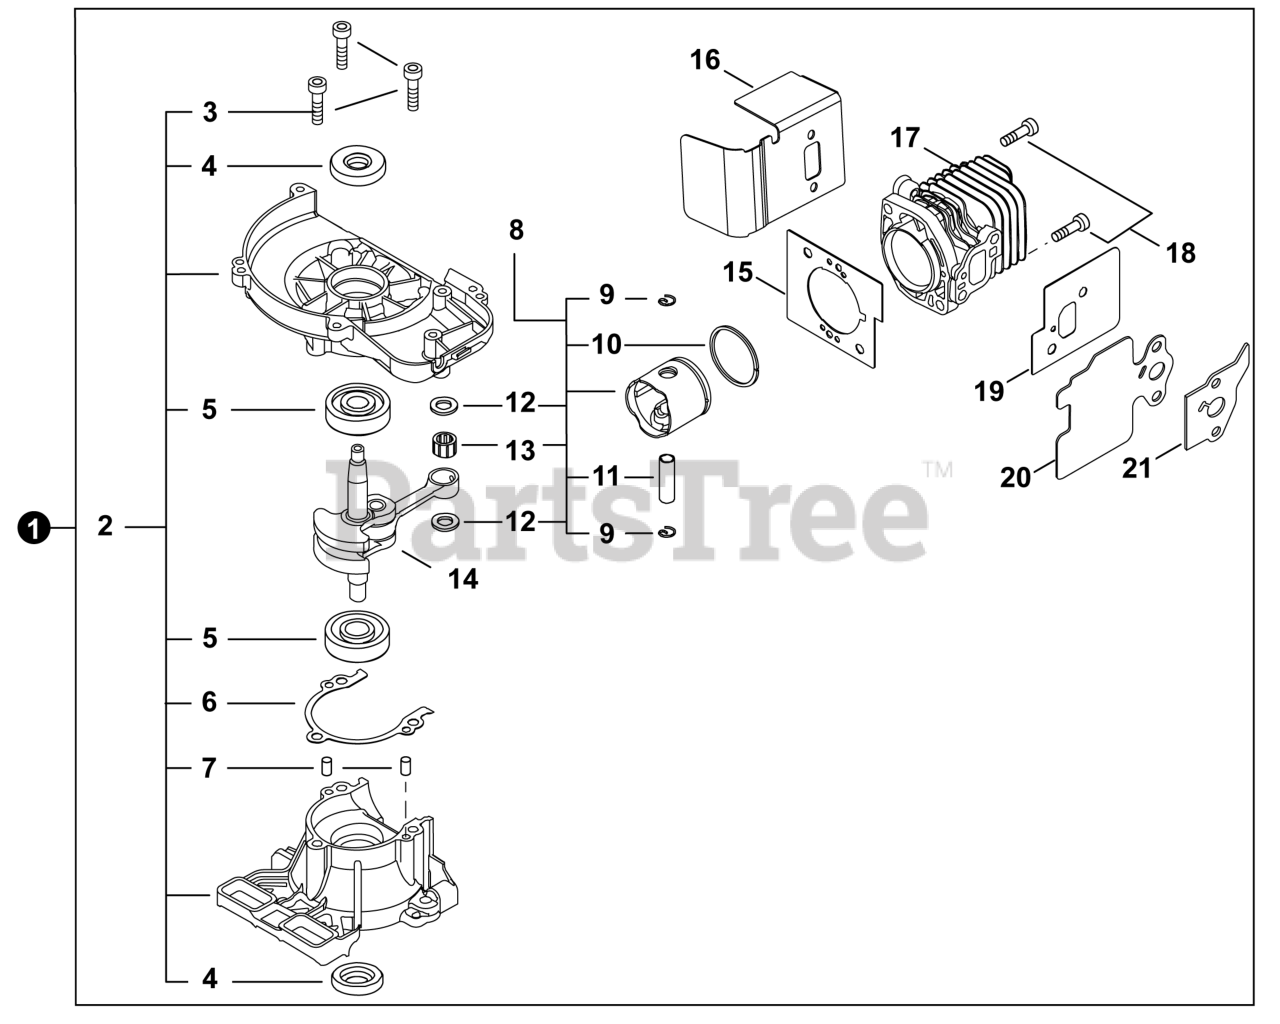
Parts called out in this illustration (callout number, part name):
1	SHORT BLOCK
2	CRANKCASE KIT
3	BOLT 5×28
4	SEAL, OIL
5	BEARING, BALL
6	GASKET, CRANKCASE
7	PIN, LOCATING 4×8
8	PISTON KIT
9	RING, SNAP
10	RING, PISTON
11	PIN, PISTON 8
12	WASHER, THRUST
13	BEARING, NEEDLE
14	CRANKSHAFT ASSY
15	GASKET, CYLINDER
16	HEAT SHIELD, EXHAUST
17	CYLINDER
19	GASKET, INTAKE
20	HEAT SHIELD, INTAKE
21	GASKET, INTAKE
